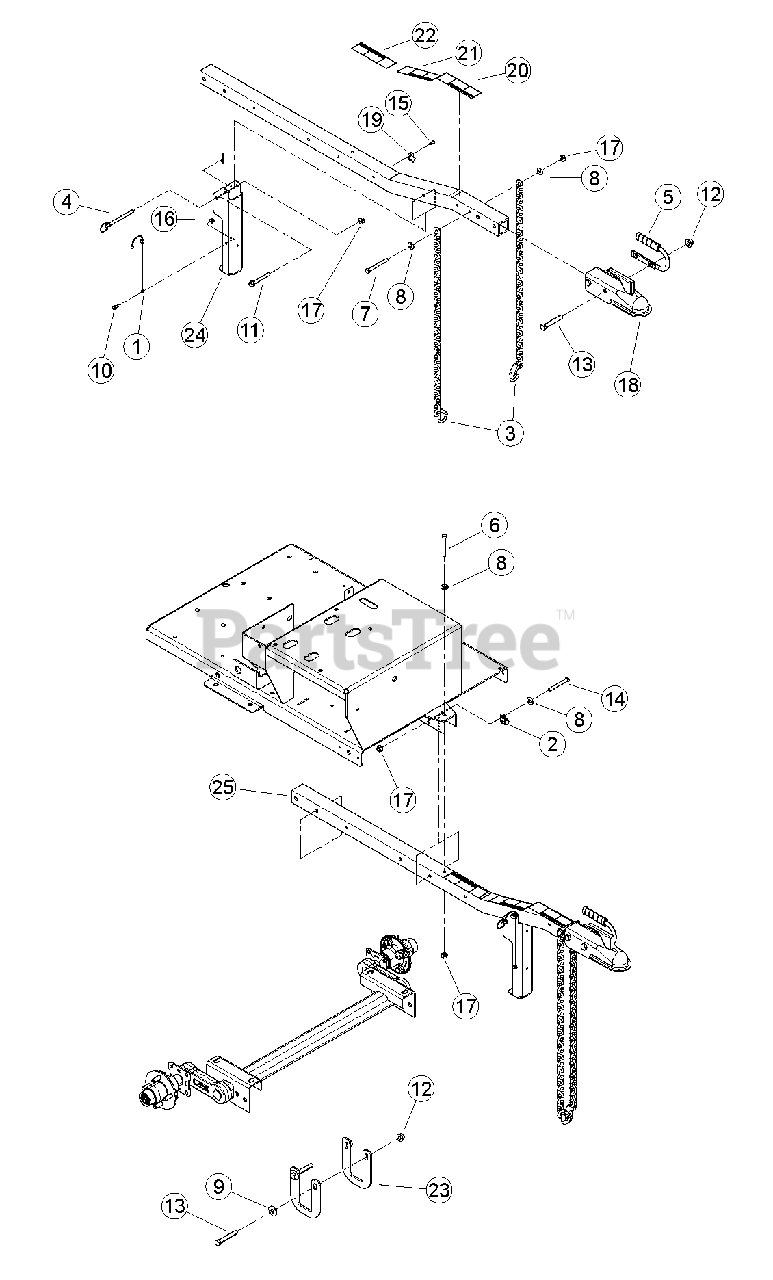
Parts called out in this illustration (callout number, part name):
1	LANYARD, NYLON
2	CLAMP, 9/16 COATED
3	CHAIN, SAFETY 5000 LB W/ LATCH
4	PIN, 3/8 HITCH
5	HANDLE, HITCH COUPLER
6	BOLT, 3/8 X 3 GR5 HEX CAPSCREW ZP
7	BOLT, 3/8 X 3-1/2" HEX HD GR5 ZP
8	WASHER, 3/8" FLAT ZP
9	WASHER, 1/2" FLAT ZP
10	BOLT, 1/4-20 X 3/4 HWH GR5 CZP
11	BOLT, 3/8 X 3 FLANGE NC
12	NUT, 1/2-13 NYLOCK FLANGE
13	BOLT, 1/2 X 3-1/4 HCS GR5 ZP
14	BOLT, 3/8 X 3-1/4 HEX HD GR5 ZP
15	RIVET, AL BLIND 1/4 X 3/4 DOME HEAD
16	NUT, 1/4-20 NYLOCK-FLANGE
17	NUT, 3/8-16 NYLOCK-FLANGE
18	TRAILER HITCH COUPLER
19	CLAMP, CABLE MOUNT
20	DECAL, SAFETY CHAINS
21	DECAL, TRAILER ELECTRICAL
22	DECAL, SAFE COUPLING
23	PLATE, HITCH SADDLE
24	POLE, C/S HITCH
25	WELDMENT, STAND JACK
